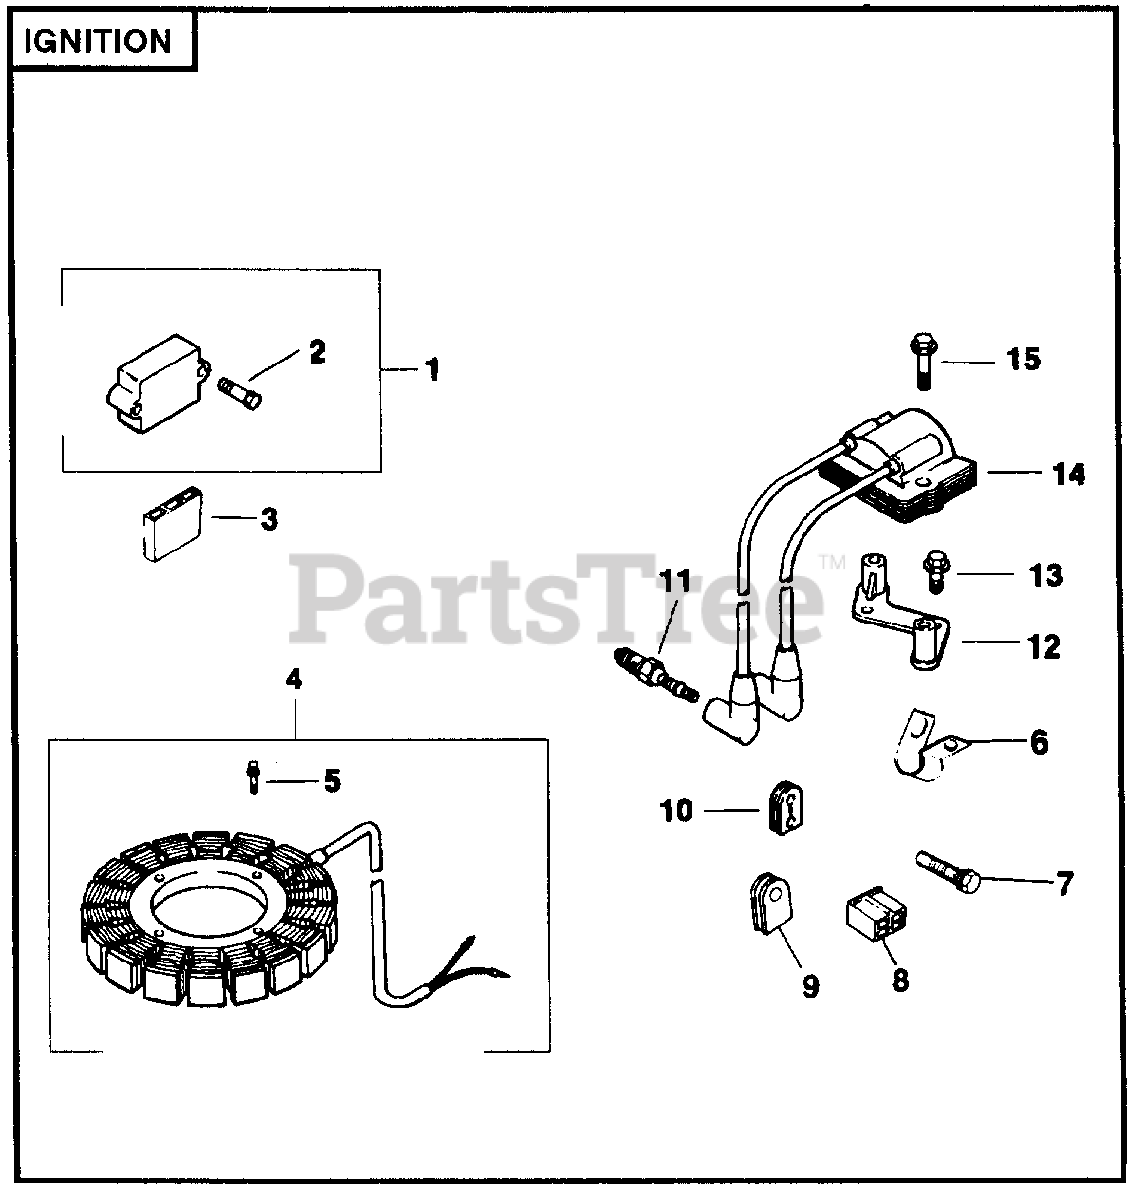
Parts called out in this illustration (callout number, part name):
2	SCREW
3	CONNECTOR
4	KIT
5	SCREW
6	CLIP
7	SCREW
9	GROMMET
13	SCREW, 1/4-20 X 1
